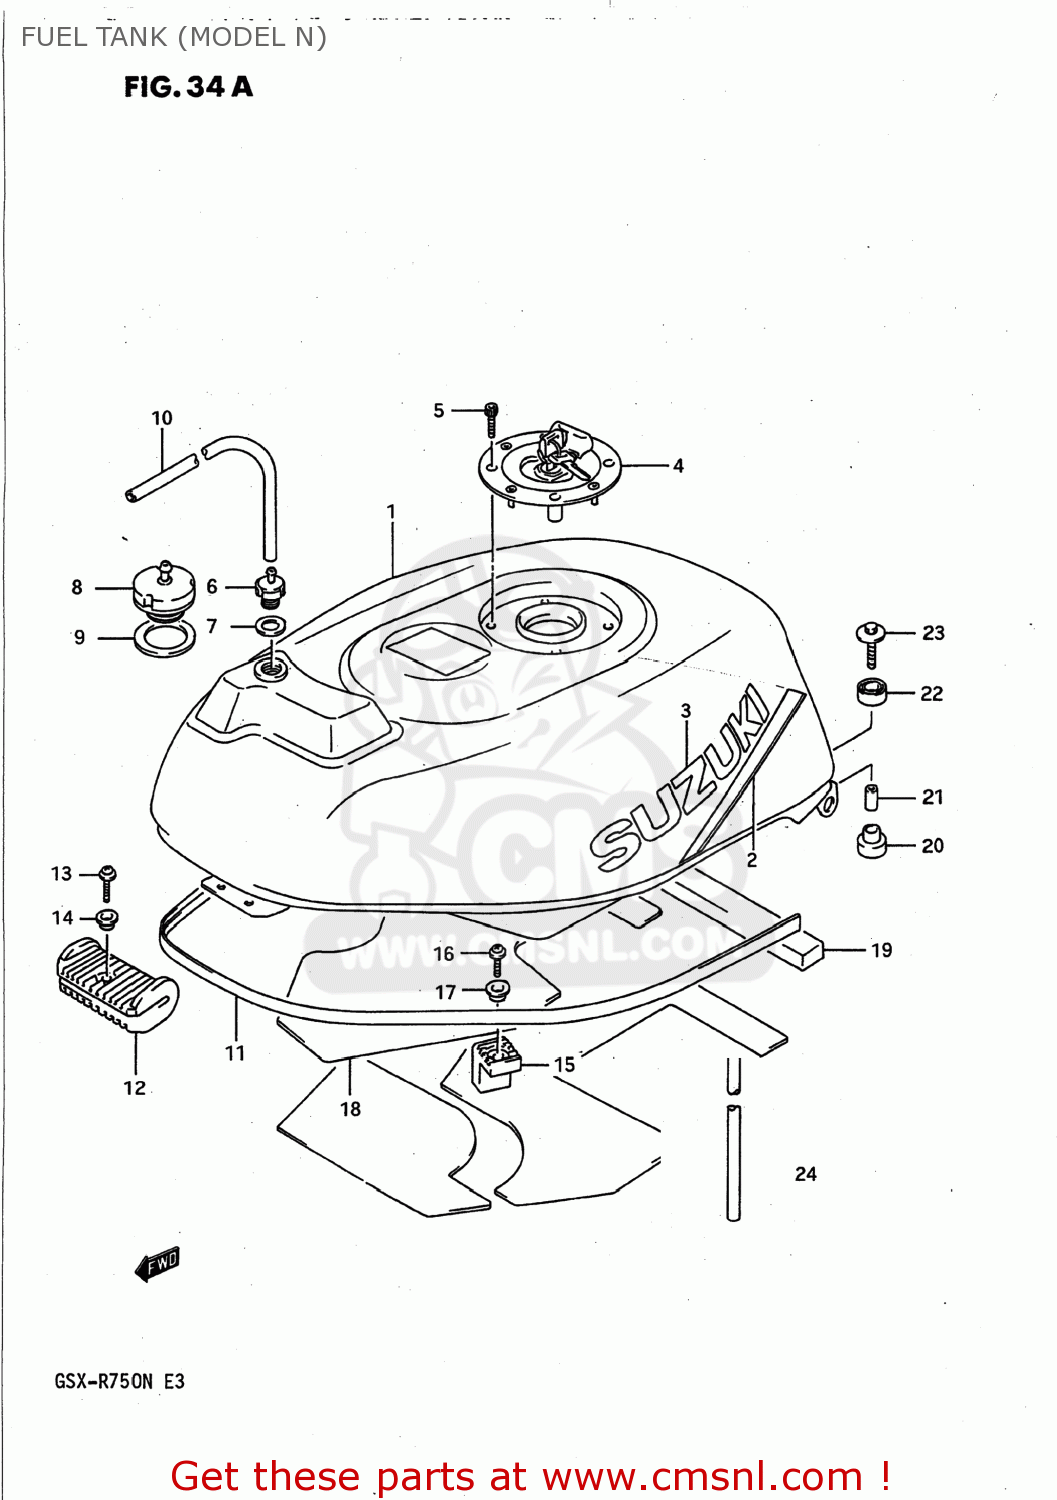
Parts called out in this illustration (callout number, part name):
1	TANK ASSEMBLY,FUEL
2	TAPE SET,FUEL TANK STRIPE
3	EMBLEM,FUEL TANK
4	CAP SET,FUEL TANK
5	BOLT(5X20)
6	PLUG,FUEL TANK BREATHER
7	GASKET(12.5X20X2.5) (NAS)
8	(CA) VALVE,FUEL TANK BREATHER
9	GASKET 27X40X2.5 (NAS)
10	HOSE(5X8.2X600)
11	MOLDING,FUEL TANK
12	CUSHION,FUEL TANK FR
13	SCREW 5X10
14	WASHER
15	CUSHION,FUEL TANK SIDE
16	SCREW
17	WASHER
18	SHIELD,FUEL TANK HEAT
19	CUSHION, AIR SEAL
20	CUSHION
21	SPACER
22	CUSHION
23	BOLT(6X35)
24	HOSE
